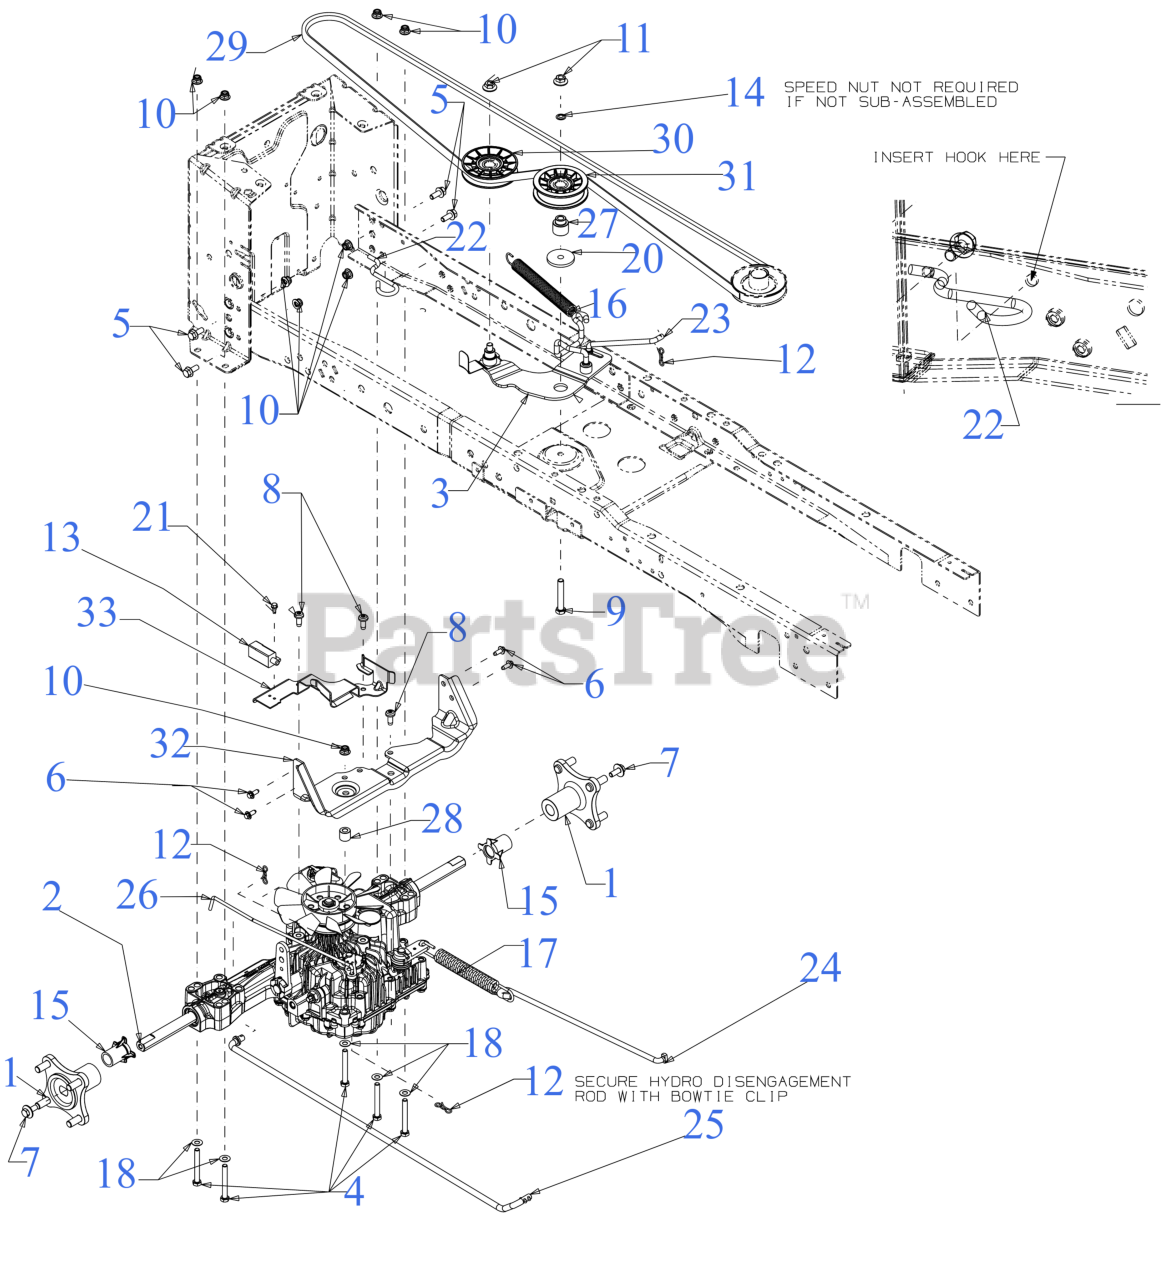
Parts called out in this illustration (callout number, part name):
1	WHEEL HUB ASSEMBLY DBL D
2	TRANSMISSION ASSEMBLY
3	IDLER BRACKET ASSEMBLY
4	SCREW 5/16-18 x 2.5 GR 5
5	SCREW 5/16-18
6	SCREW M6-1 x .625
7	SCREW 5/16-24 x .85 GR5
8	SCREW 5/16-18 x .750
9	SCREW 3/8-16 x 2.25 GR5
10	FLANGE LOCK NUT 5/16-18
11	FLANGE LOCK NUT
12	BOW TIE COTTER PIN 1/4-5/16
13	INTERLOCK SWITCH (NO/NC)
15	AXLE SLEEVE .765 ID x 1.575 LG
16	EXTENSION SPRING .790 DIA x 8.41
17	EXTENSION SPRING 0.90 DIA x 8.14
18	FLAT WASHER
20	SHOULDER SPACER
21	SHOULDER SCREW
22	DECK SPRING HOOK
23	IDLER BRACKET ROD
25	HYDRO CONTROL ROD
26	HYDRO DISENGAGEMENT ROD
27	SHOULDER SPACER
28	SPACER .34 x .75 x .63 LG
29	V-BELT A SEC x 90.90
29	Cub Cadet DRIVE BELT
29	Genuine Factory Parts DRIVE BELT
30	V-IDLER PULLEY 3.56 OD
31	FLAT IDLER PULLEY 3.00 OD
32	TRANSMISSION MOUNTING BRACKET
